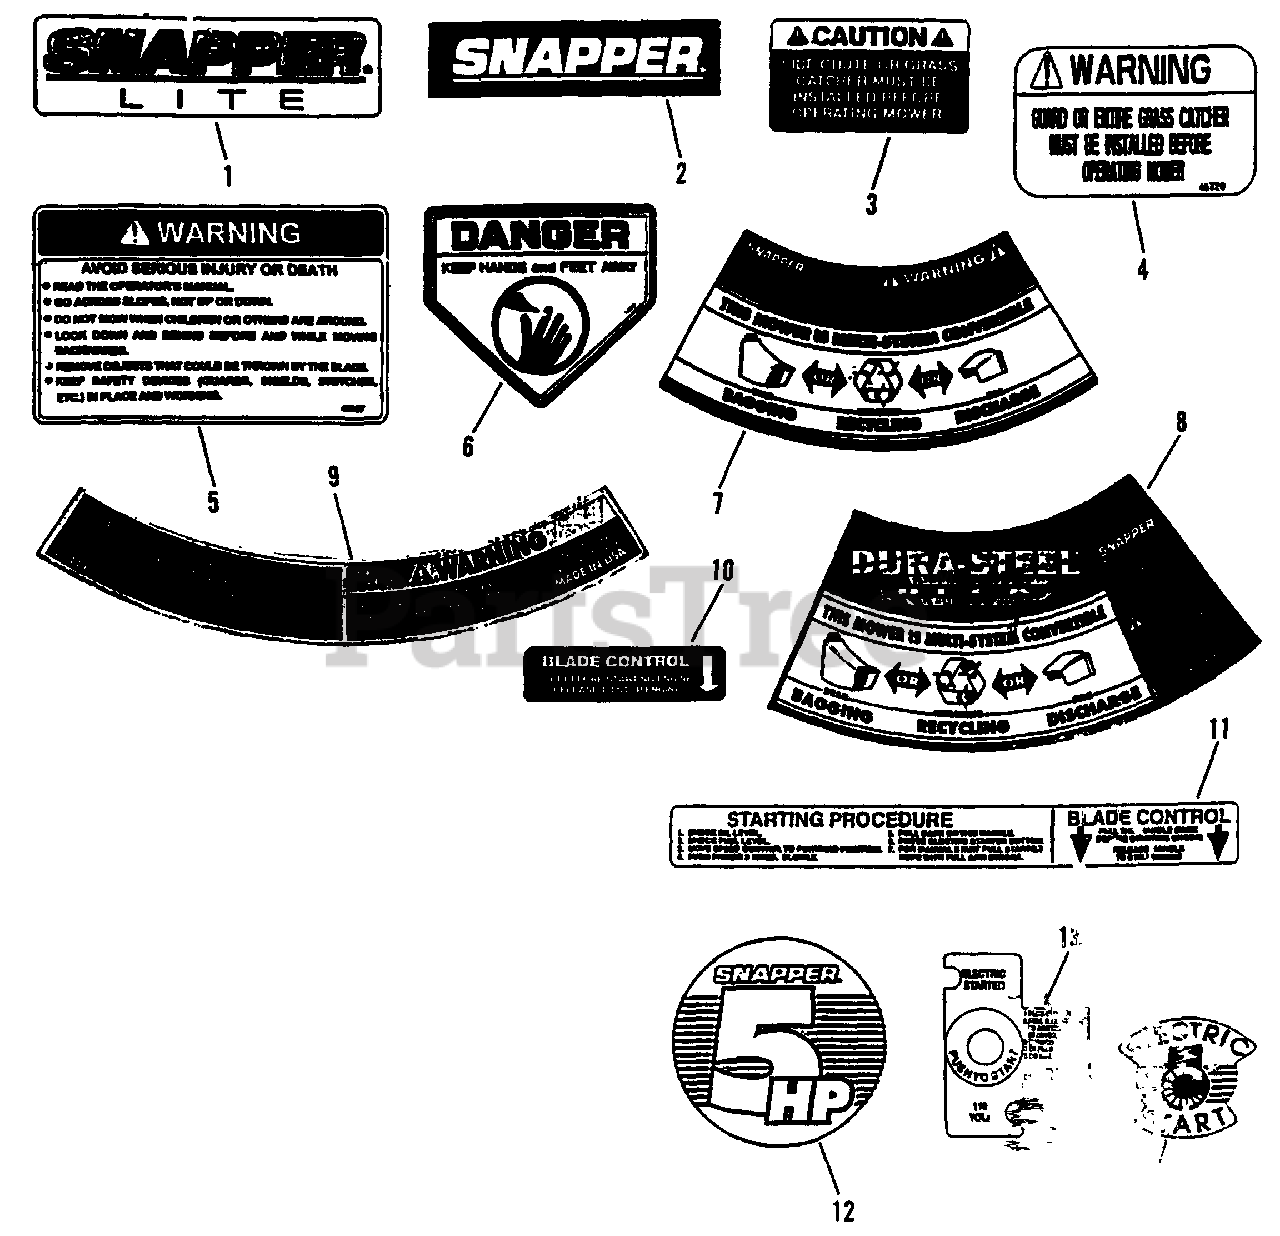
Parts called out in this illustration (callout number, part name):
1	DECAL, Snapper "LITE"
2	DECAL, Snapper
3	DECAL, CAUTION (Discharge Opening)
4	DECAL, Chute/Opening
5	DECAL, WARNING 1997
6	DECAL, DANGER (Keep Hands & Feet Away)
7	DECAL, Feature/Compliance
8	DECAL, DECAL, Dura Steel
9	DECAL, DECAL, Warning (Deck)
10	DECAL, Blade Control
11	DECAL, Starting Procedure ES
12	DECAL, Snapper/5HP
13	DECAL, Starting Button ES
14	DECAL, Electric ST. L.G.
